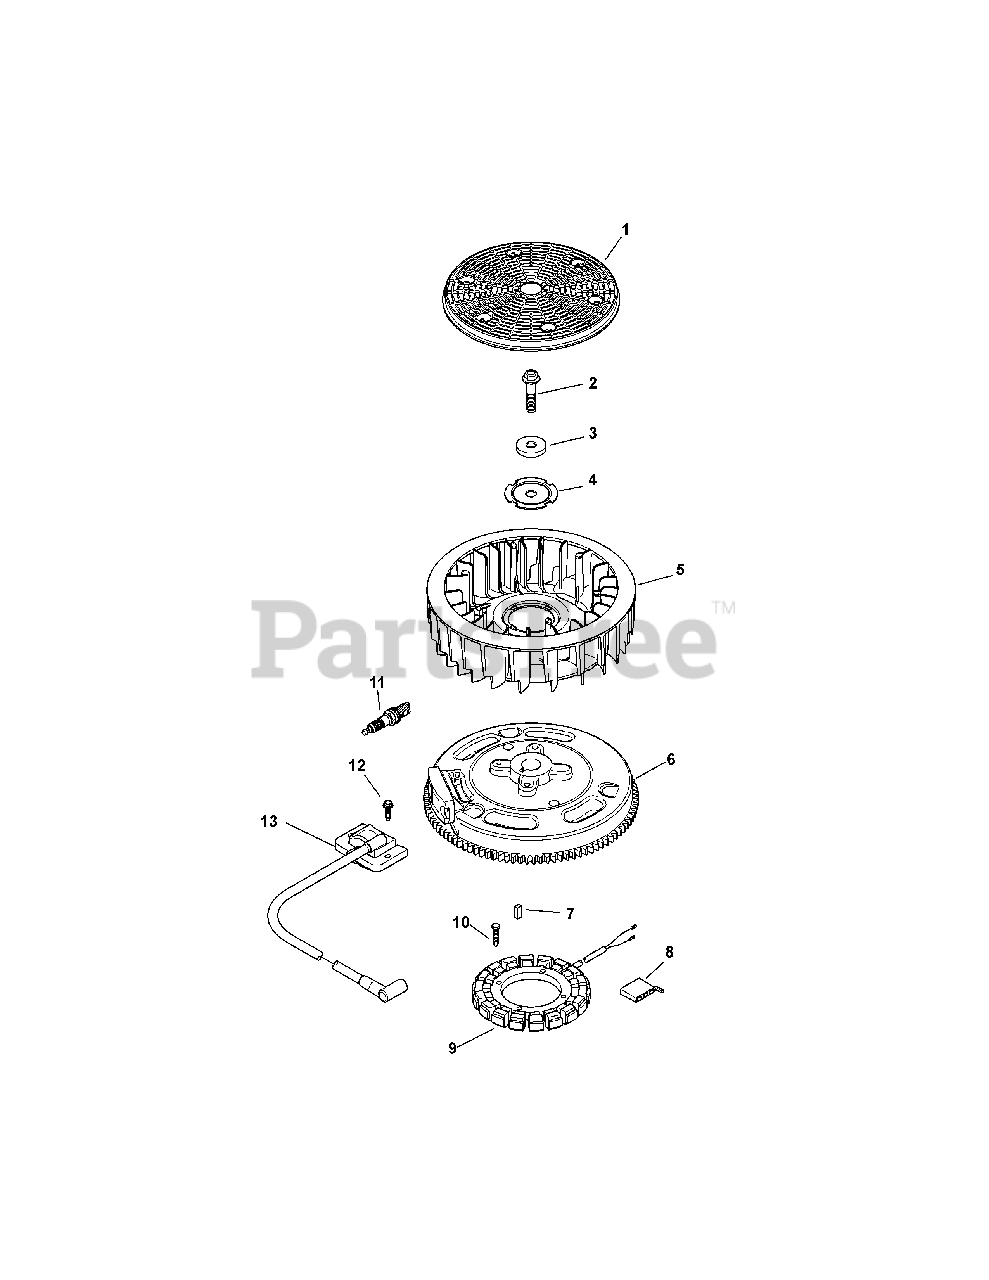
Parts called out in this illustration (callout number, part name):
1	Screen, Grass
2	Screw, Hex Flange
4	Plate, Fan Mounting
5	Fan
6	Flywheel Assembly (Sv710/Sv730)
9	Kit, 15 / 20 Amp Stator
10	Screw, Thd Frm M5X0.8X25
11	Plug, Spark (Std)
12	Screw, Flg Thd Frm M5X.8X20
13	Kit, Module Igntn (Cdi ! Fixed)
